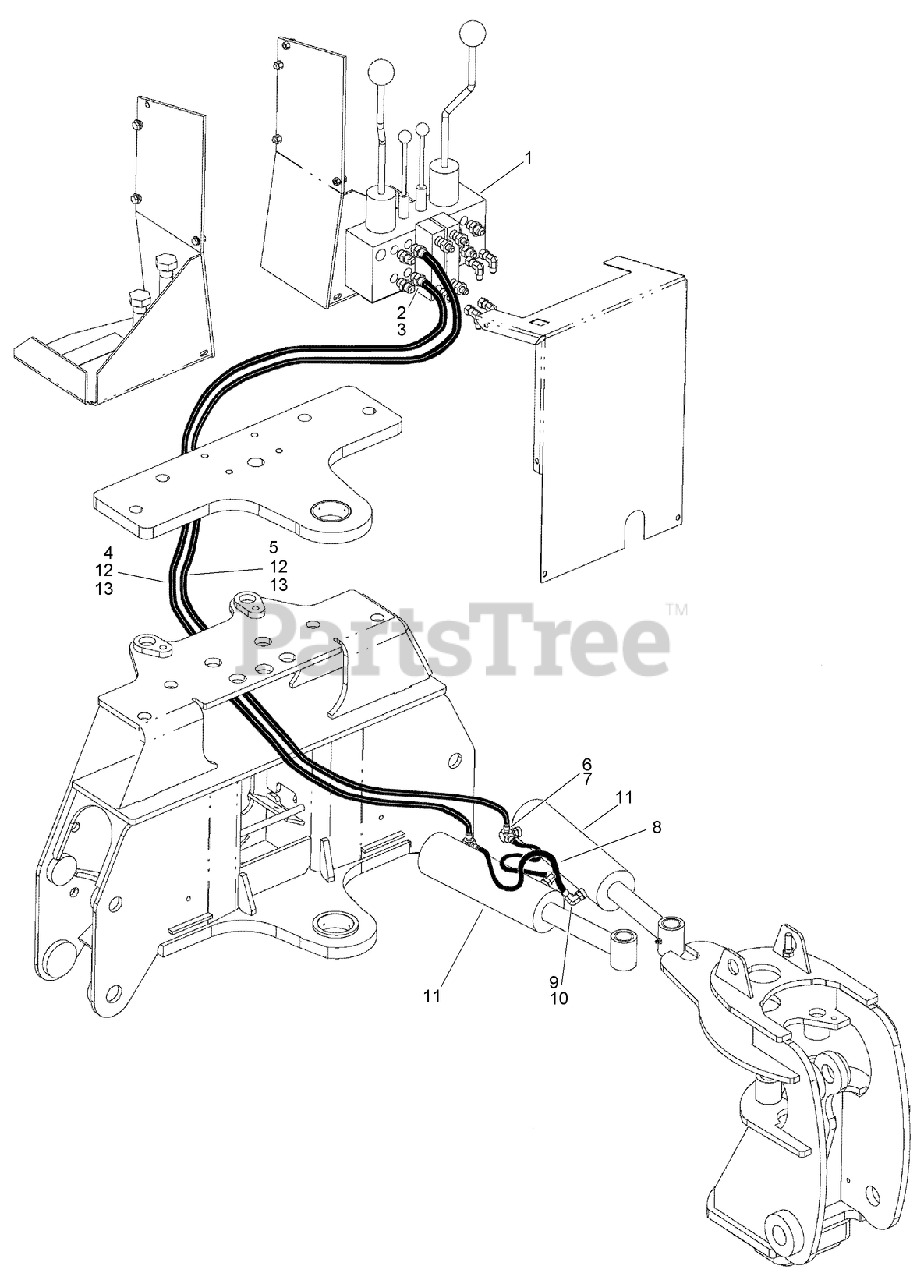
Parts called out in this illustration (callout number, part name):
1	HYD CONTROL VALVE ASM
2	CONNECTOR-Str Thd 1/2, 37FL-ORB 1/2
3	O-RING
4	HOSE-Hydraulic, Swing Cylinder
5	HOSE-Hydraulic, Swing Cylinder
6	FITTING
7	O-RING
9	ELBOW-90 DEG (ADJUSTABLE 37 DEG)
10	O-RING
11	HYD CYLINDER ASM
12	HOSE PROTECTOR
13	STRAP-TIE
